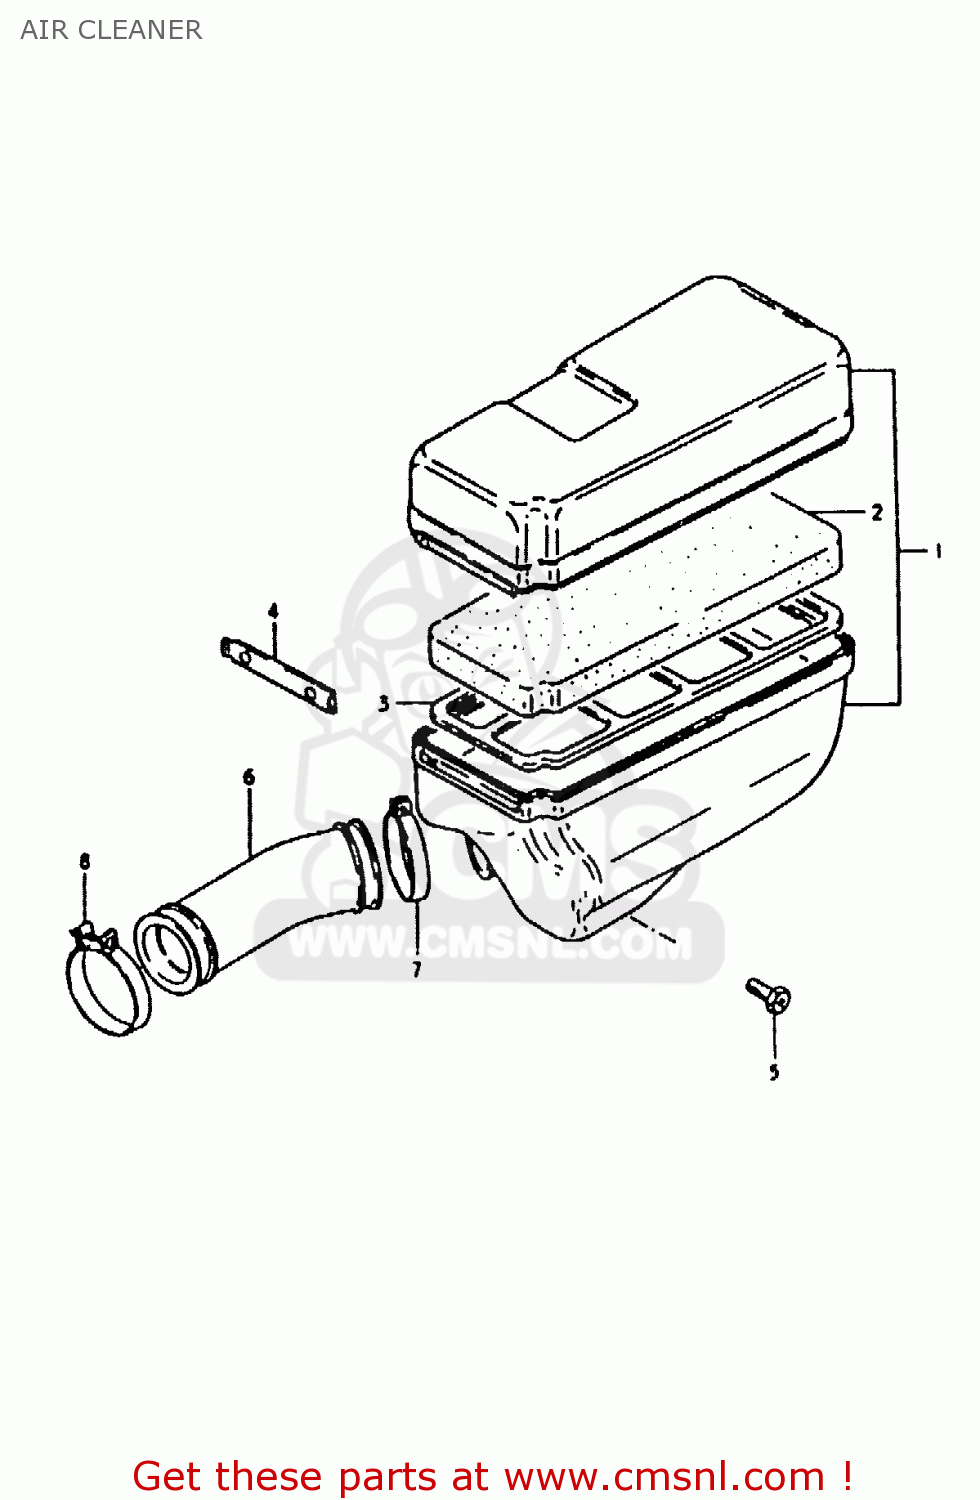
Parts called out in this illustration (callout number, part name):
1	CLEANER ASSY,A
2	FILTER
3	HOLDER
4	SLIDER
5	SCREW
6	TUBE,AIR CLEANER OUTLET
7	CLAMP
8	CLAMP
